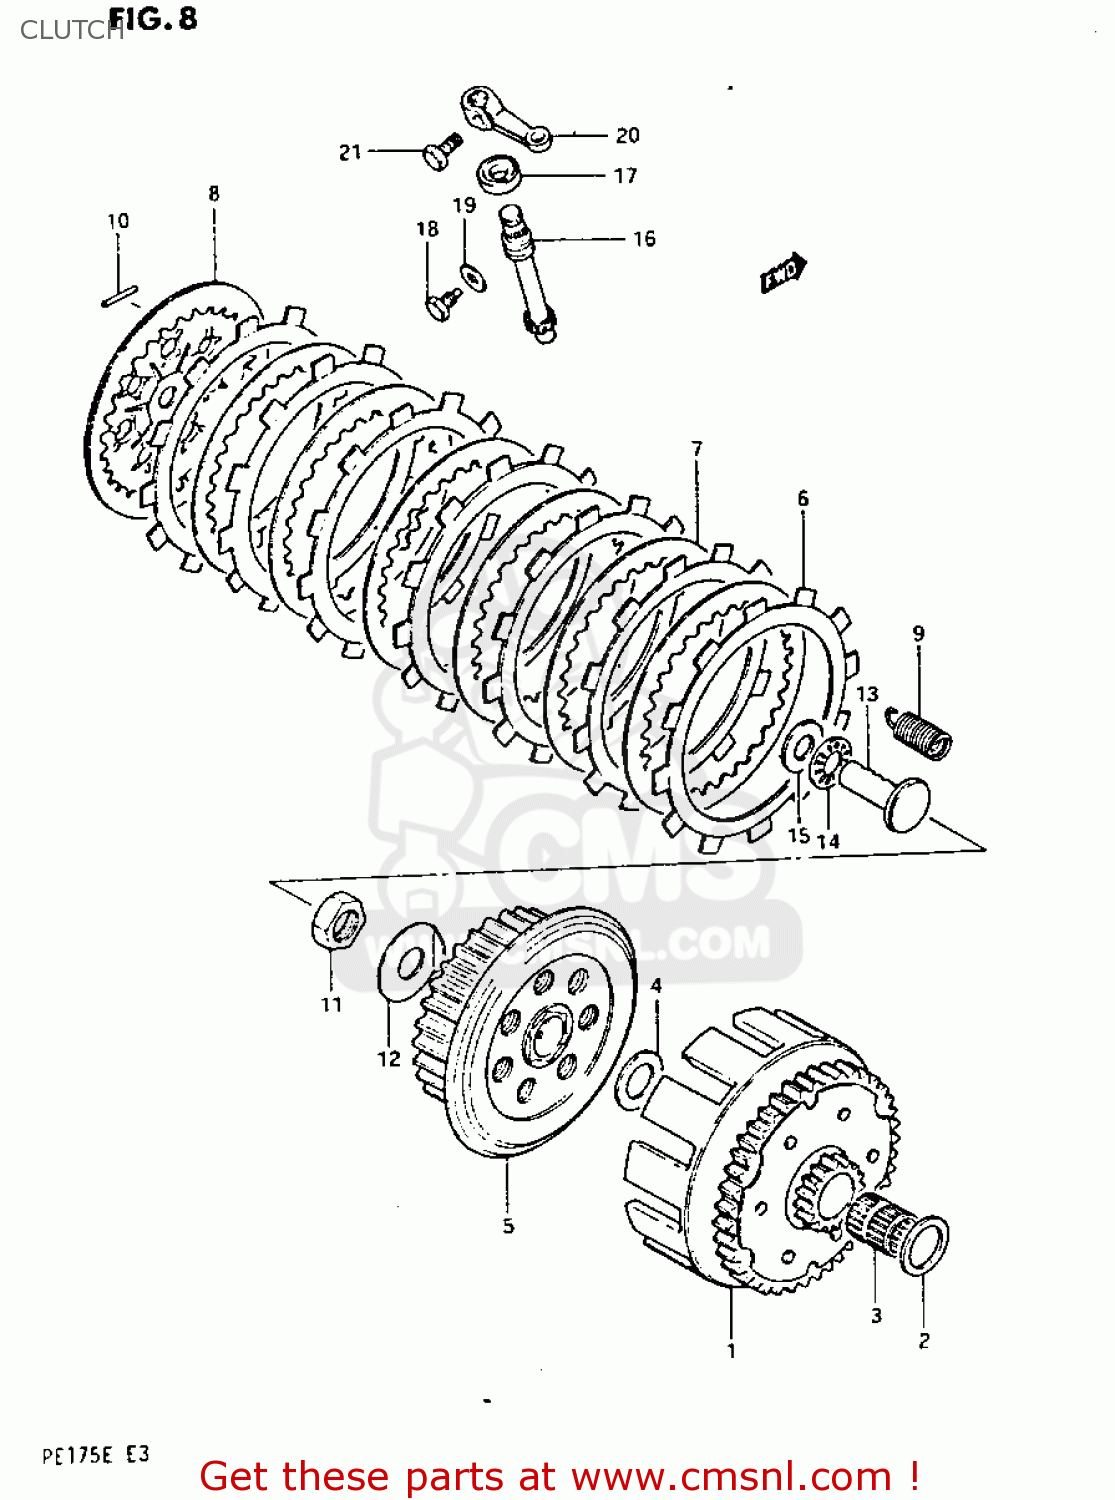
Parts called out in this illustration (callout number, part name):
1	GEAR ASSEMBLY,PRIMARY DRIVE
2	WASHER
3	BEARING(20X25X26)
4	WASHER
5	HUB,CLUTCH SLEEVE
6	PLATE,CLUTCH DRIVE(T:3.0) (NAS)
7	PLATE,CLUTCH DRIVEN
8	PLATE,CLUTCH PRESSURE
9	SPRING
10	PIN(2.5X19.8)
11	NUT
12	WASHER,LOCK
13	RACK,CLUTCH RELEASE
14	BEARING(10X22X2.8)
15	WASHER(10.1X21.4X0.8)
16	PINION,CLUTCH RELEASE
17	SEAL,OIL (10X17X5)
18	BOLT(6X12)
19	WASHER
20	ARM,CLUTCH RELEASE
21	BOLT
